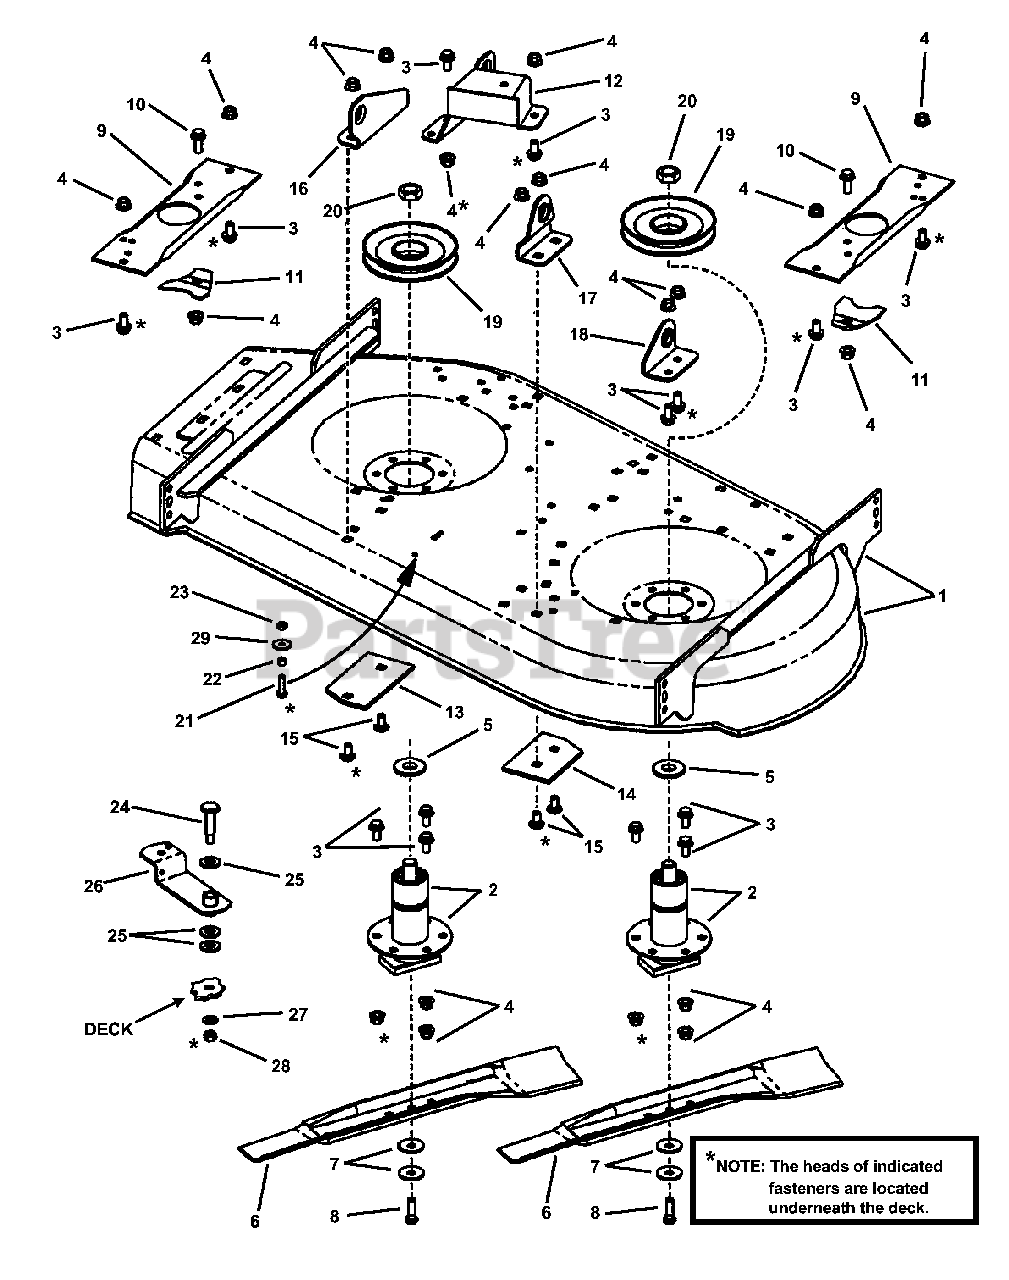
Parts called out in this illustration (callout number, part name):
1	DECK, 42" Replacement
2	ASSEMBLY, Spindle Brake
3	BOLT, 3/8-16 x 3/4" Hex Flange Lock, Grade 5
4	NUT, 3/8-16 Hex Fl. Lock
5	WASHER, Spindle
6	BLADE, 21" Standard Lift
7	WASHER, Cone
8	SCREW, 3/8-24 x 1-1/4" Hex Head Cap, Grade 5
9	BRACE, Spindle
10	BOLT, 3/8-16 x 1" Hex Flange Lock, Grade 5
11	ASSEMBLY, Spindle Lock
12	IDLER, Stationary
13	REINFORCEMENT, R.H.
14	REINFORCEMENT, L.H.
15	BOLT, 3/8-16 x 3/4" Short Neck Carriage, Grade 5
16	BRACKET, R.H. Front Lift
17	BRACKET, L.H. Front Lift
18	BRACKET, L.H. Rear Lift
19	PULLEY, 5-1/4"
20	NUT, 3/4-16 Hex Flange Jam, Grade 8
21	BOLT, 1/4-20 x 1-1/8, Grade 5
22	SPACER, .26 x .3
23	NUT, 1/4-20 Hex Center Lock
24	SHOULDER BOLT, 3/8-24 x 5/8"
25	WASHER, 1/2" I.D. x 1-1/16" O.D. Flat
26	IDLER ARM
27	WASHER, 3/8" Flat
28	NUT, 3/8-24 Hex Center Lock
29	WASHER, 1/4" Flat
